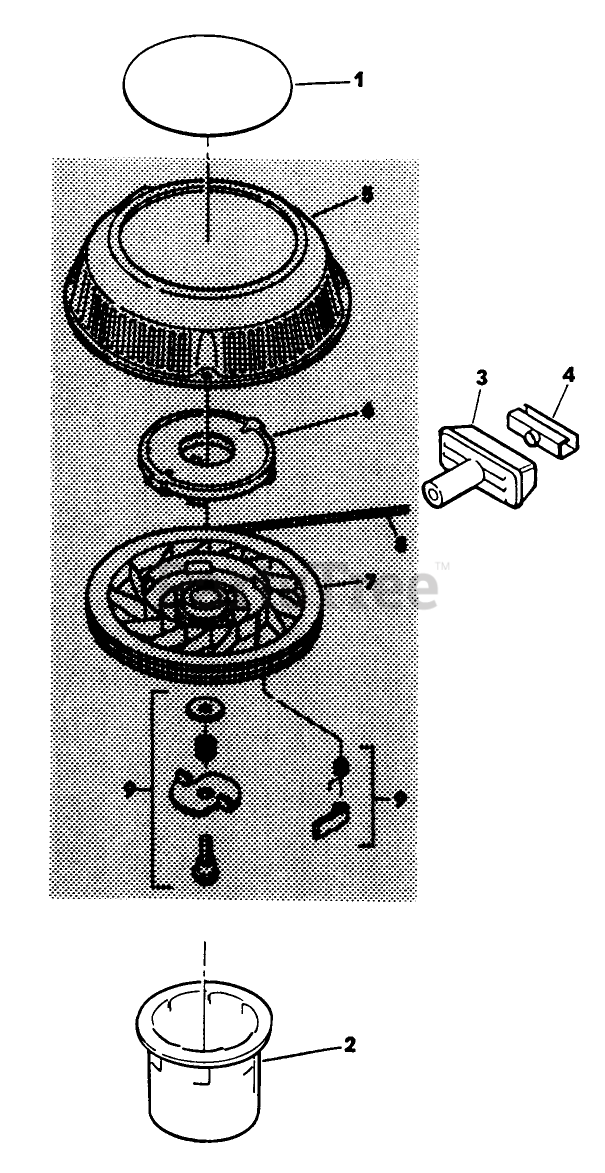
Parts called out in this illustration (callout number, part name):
2	HUB-STARTER E COMM.
4	CLIP-STARTER
7	PULLEY
9	DOG KIT
